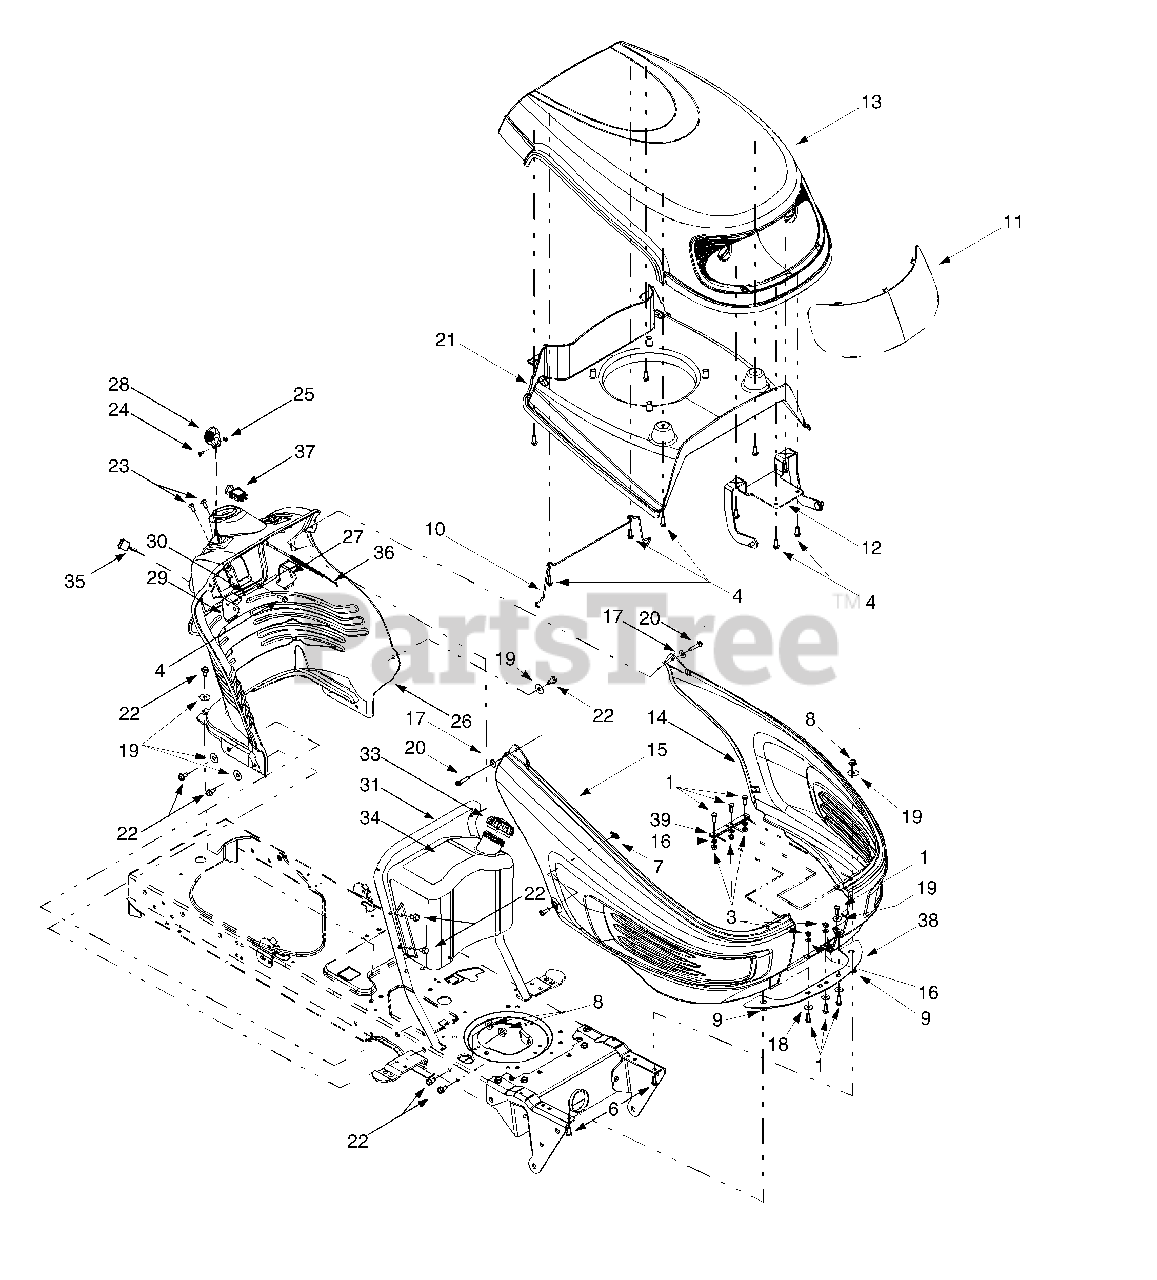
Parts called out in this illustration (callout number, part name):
1	Hex Cap Screw, 1/4-20 x .75
3	Hex Nut, 1/4-20
4	Self-tapping Screw, 1/4-15 x .75
6	Hex Cap Screw, 5/16-18 x 1.25
7	U-type Speed Nut, 1/4-20
8	Flange Lock Nut, 5/16-18
10	Hood Latch Rod
11	Head Light Lens
14	LH Side Panel
15	RH Side Panel
16	Lock Washer, 1/4
17	Flat Washer, .283 x .75 x .030
18	Flat Washer, .28 x .74 x .063
19	Flat Washer, .349 x 1.0 x .063
20	Self-tapping Screw, 1/4-20 x 1.25
22	Self-tapping Screw, 5/16-18 x .625
23	Torx Self-tapping Screw, 1/4-14 x .625
24	Torx Screw, #8-32 x .375
25	Hex Nut, 8-32
26	Dash Panel, 4-style
27	Parking Brake Button
28	Throttle Control Lever
29	Cruise Control Button
30	Brake/Cruise Pivot Rod
33	Fuel Cap
34	Fuel Tank, 3-gallon
35	Ignition Key w/ plastic cover
36	Choke Cable
37	Electric PTO Switch
